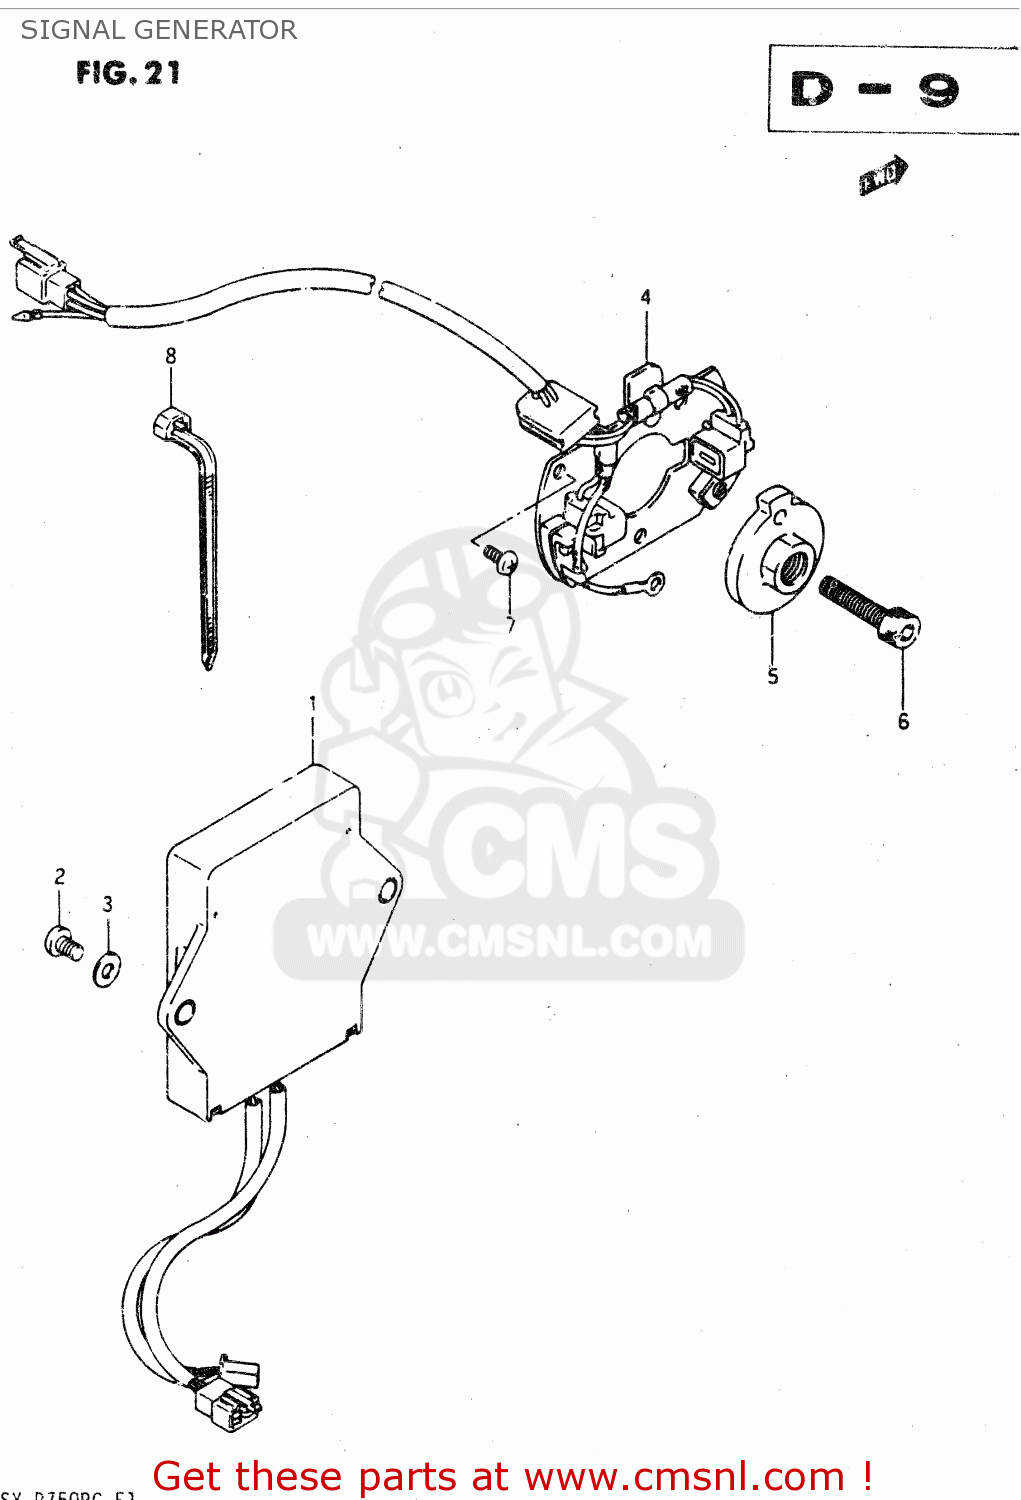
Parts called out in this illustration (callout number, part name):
1	IGNITER UNIT
2	SCREW
3	WASHER, LOWER
4	GENERATOR ASSEMBLY,SIGNAL
5	ROTOR COMP,SIGNAL
6	BOLT
7	SCREW
8	CLAMP(L:95)
